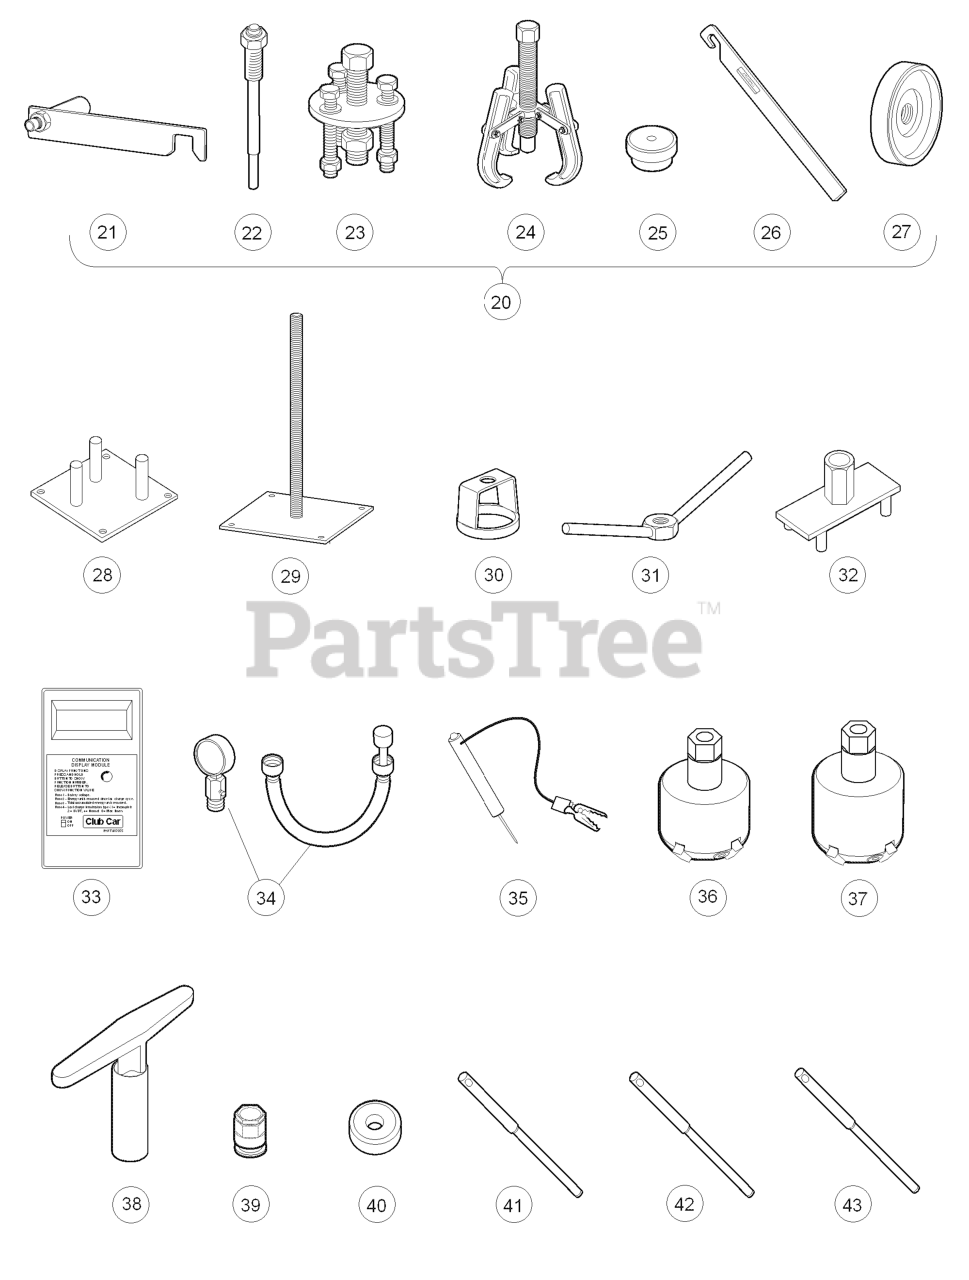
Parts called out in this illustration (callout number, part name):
20	C.C. CLUTCH TOOL KIT
21	TOOL, CLUTCH ALIGNMENT
22	TOOL, CLUTCH PULLER
23	CLUTCH DRIVE HUB PULLER
24	DRIVEN CLUTCH CAM PULLER
25	DRIVEN CLUTCH PULLER PLUG
26	DRIVE CLUTCH HOLDER TOOL ASM.
27	PRESS WELDMENT
28	TOOL-STATIONARY PRIMARY
29	TOOL-SPRING COMPRESSION BASE
30	TOOL-SPRING COMPRESSION COLAR
31	TOOL-SPRING COMPRESSION COLAR
32	TOOL-SPIDER PRIMARY
33	COMMUNICATION DISPLAY MODULE
34	COMPRESSION GUAGE AND ADAPTER
35	CONTINUITY TESTER
36	CUTTER, VALVE SEAT, #122
37	CUTTER, VALVE SEAT, #115
38	ADAPTER, T-WRENCH
39	ADAPTER, T-WRENCH
40	Cutter, Valve Seat, 60 Degree
41	PILOT, 6.6 MM
42	PILOT, 6.62 MM
43	PILOT, 6.65 MM
